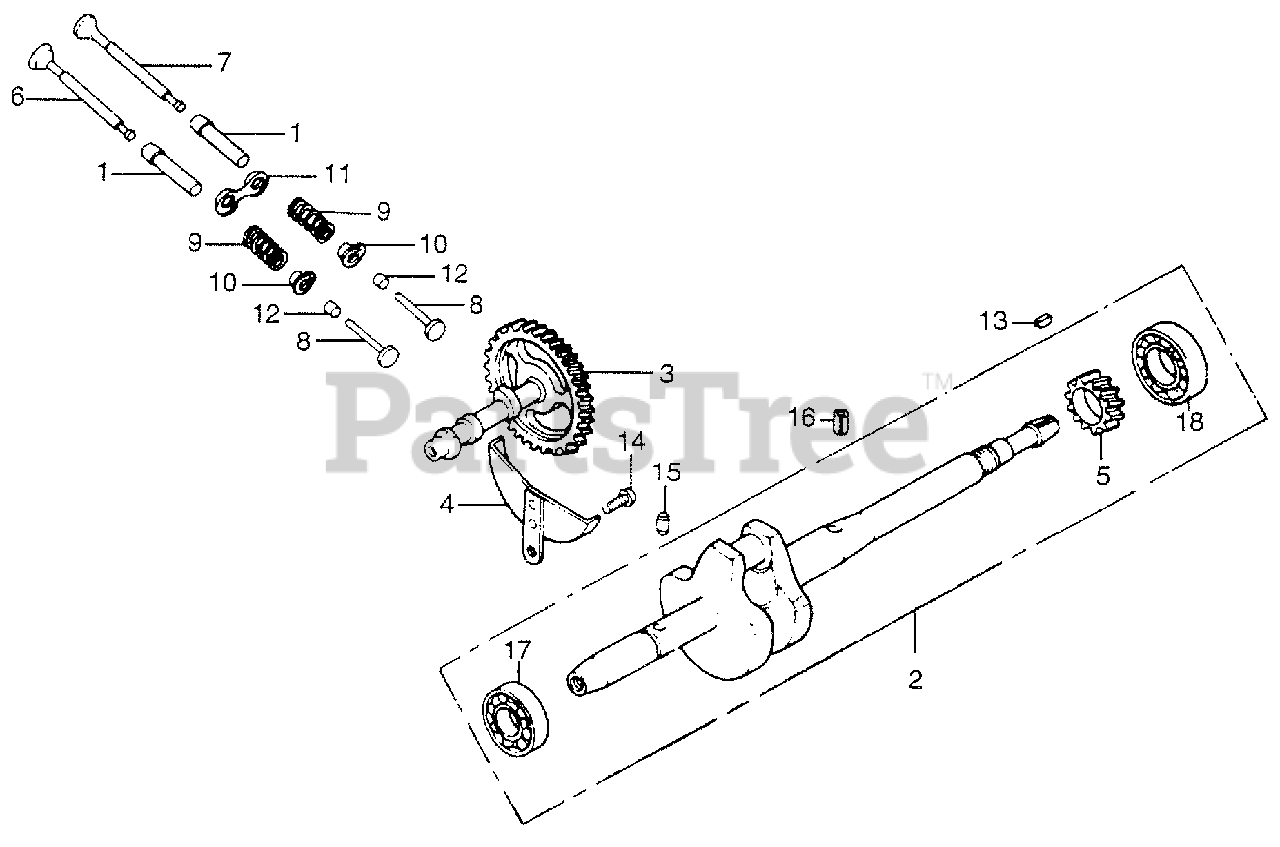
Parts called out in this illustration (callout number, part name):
1	GUIDE, VALVE (OS) (NOT AVAILABLE)
2	CRANKSHAFT
3	CAMSHAFT (NOT AVAILABLE)
5	GEAR, TIMING
6	VALVE, IN. (NOT AVAILABLE)
7	VALVE, EX.
8	LIFTER, VALVE (NOT AVAILABLE)
9	SPRING, VALVE (NOT AVAILABLE)
10	RETAINER, VALVE SPRING (NOT AVAILABLE)
11	SEAT, SPRING (NOT AVAILABLE)
12	ADJUSTER, TAPPET CLEARANCE (3. 48-3.51)
12	ADJUSTER C, TAPPET CLEARANCE (3.42-3.45) (NOT AVAILABLE)
12	ADJUSTER F, TAPPET CLEARANCE (3.33-3.36) (NOT AVAILABLE)
12	ADJUSTER, TAPPET CLEARANCE (3.24-3.27) (NOT AVAILABLE)
12	ADJUSTER, L. TAPPET CLEARANCE (3.15-3.18) (NOT AVAILABLE)
12	ADJUSTER, TAPPET CLEARANCE (3.06-3.09) (NOT AVAILABLE)
13	KEY, WOODRUFF (16X7) (NOT AVAILABLE)
14	SCREW, PAN (5X10)
15	PIN, DOWEL (4X65) (NOT AVAILABLE)
16	PIN, SPRING (5X10)
17	BEARING, RADIAL BALL (6202)
18	BEARING, RADIAL BALL (6203)
